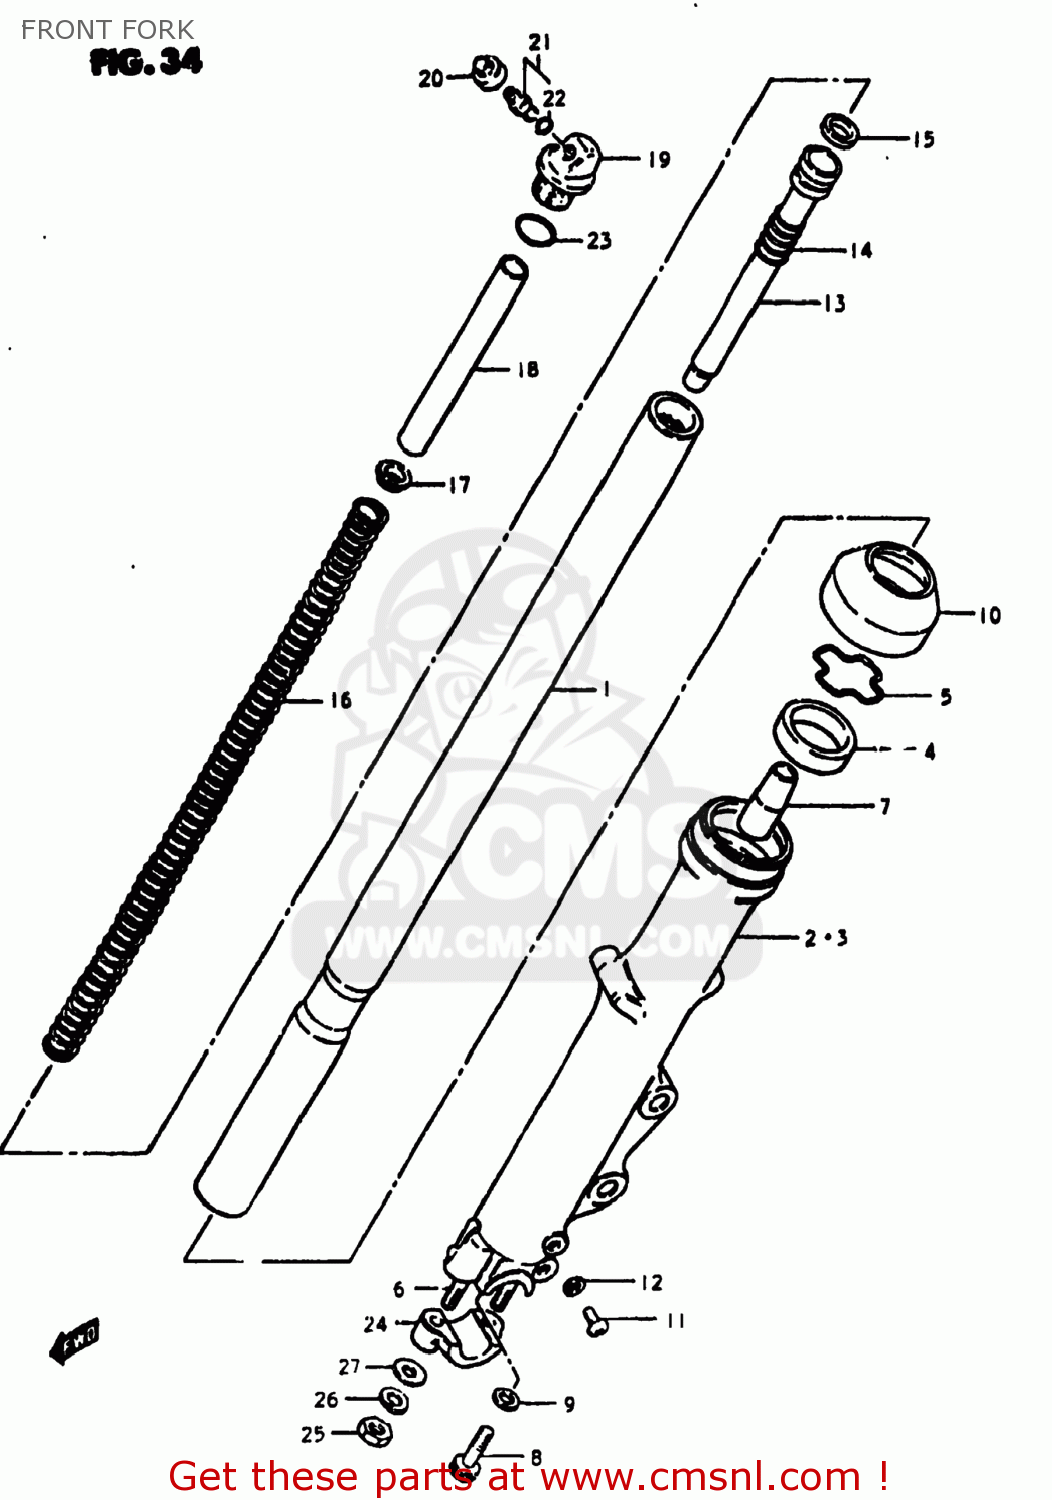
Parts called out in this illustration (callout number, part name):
0	DAMPER ASSEMBLY,LEFT
1	TUBE,FORK,INNER
2	TUBE,FORK,OUTER,RIGHT
3	TUBE,OUTER,LEFT
4	OIL SEAL,FRONT FORK
5	RING,STOPPER
6	STUD BOLT
7	PIECE,OIL LOCK
8	BOLT,FORK CYLINDER(10X25)
9	GASKET (NAS)
10	SEAL,DUST
11	SCREW
12	GASKET,DRAIN,PLUG (NAS)
13	CYLINDER,FRONT FORK
14	SPRING,REBOUND
15	RING,PISTON
16	SPRING,MAIN
17	GUIDE,FRONT FORK SPRING C
18	SPACER,FRONT FORK SPRING
19	CAP
20	CAP,VALVE
21	VALVE
22	O RING
23	O RING
24	HOLDER,AXLE
25	NUT (8MM)
26	LOCK WASHER
27	WASHER
